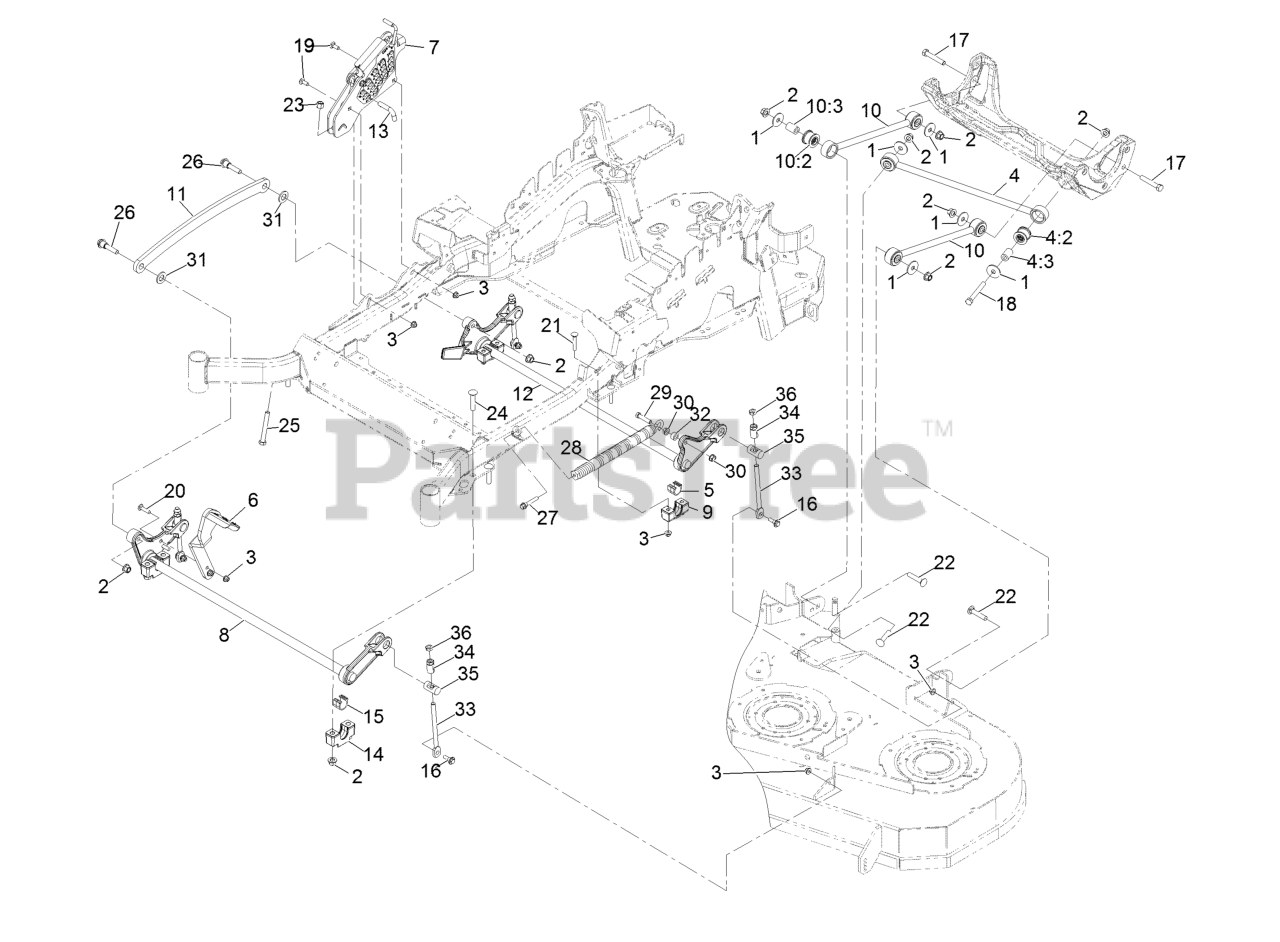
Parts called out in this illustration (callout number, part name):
1	WASHER-THRUST
2	Nut-Lock 1/2-13
3	NUT-HF, NI
4	PANHARD ROD ASM
4:2	BUSHING-SUSPENSION, RUBBER
5	BEARING-CROSS SHAFT, REAR
6	LEVER-FOOT
7	HOC ASM
8	DECKLIFT-FRONT
9	SUPPORT-CROSS SHAFT, BEARING REAR
10	DECK STRUT ASM
10:2	BUSHING-SUSPENSION, RUBBER
11	LINK-LIFT, DECK
12	LIFT-DECK, REAR
13	PIN-HOC
14	SUPPORT-CROSS SHAFT, BEARING
15	BEARING-CROSS SHAFT, FRON
16	SCREW-SHOULDER, HHF
17	SCREW-HH
18	SCREW-HH
19	BOLT-CARR
20	SCREW-CARR
21	Bolt-Carriage 3/8-16 X 2 1/4
22	SCREW-CARR
23	NUT-LOCK, NI
24	Bolt-Carriage 1/2-13 X 2 1/2 Spl Neck
25	BOLT-TAP
26	SCREW-HHF, SHOULDER
27	BOLT-SHOULDER
28	SPRING-EXTENSION
29	SCREW-HH
31	WASHER-FLAT
33	LINK-ADJUSTER, DECK LIFT
34	ADJUSTER-LIFT, DECK
35	TRUNNION
36	NUT-JAM
